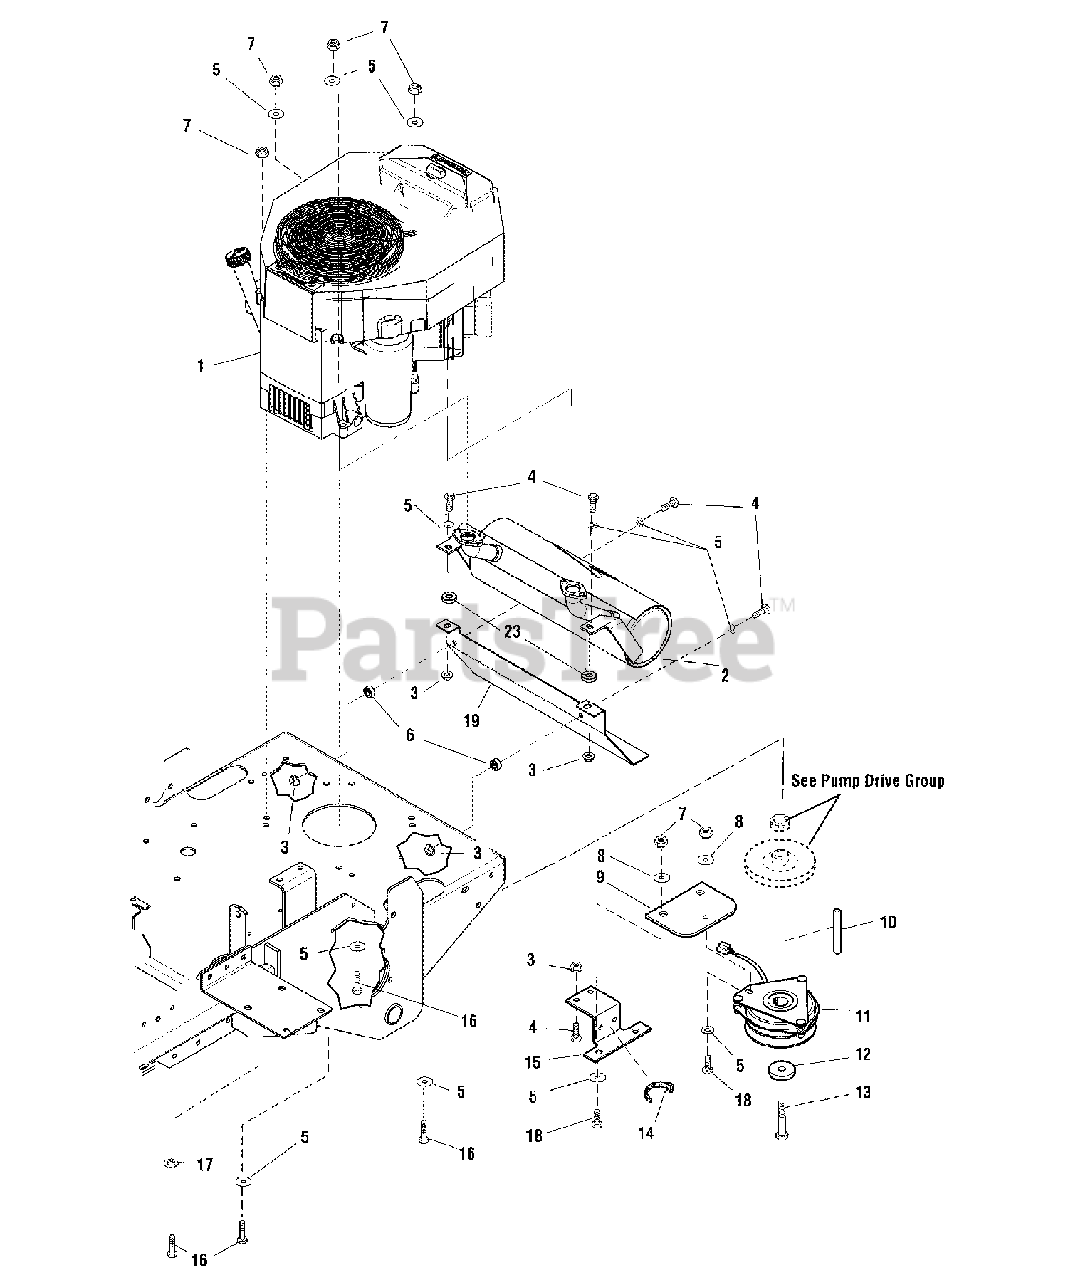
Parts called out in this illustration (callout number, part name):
1	* ENGINE, 19HP KAWASAKI
2	MUFFLER
3	NUT, HEX NYLOCK FLANGE, 5/16-18
4	BOLT, 5/16-18 X 3/4 GD5
5	WASHER, 5/16" SAE
6	SPACER, .39 X .75 X .38
7	NUT, HEX NYLON LOCK, 5/16-18
8	WASHER, CLUTCH ANCHOR, 5/16
9	CLUTCH ANCHOR PAD
10	KEY, 1/4 SQ. X 2-1/4
11	CLUTCH, ELECTRIC
12	SPACER, .45 X 1.62 X .37
13	BOLT, CRANKSHAFT, 7/16 X 3-1/4
14	TIE WRAP
15	CLUTCH ANCHOR
16	BOLT, 5/16-18 X 1-3/4
17	WASHER, 5/16 INT TOOTH LOCK
18	BOLT, 5/16-18 X 1
19	PLATE, HEAT SHIELD
23	SPACER, .39 X 1.00 X .38
